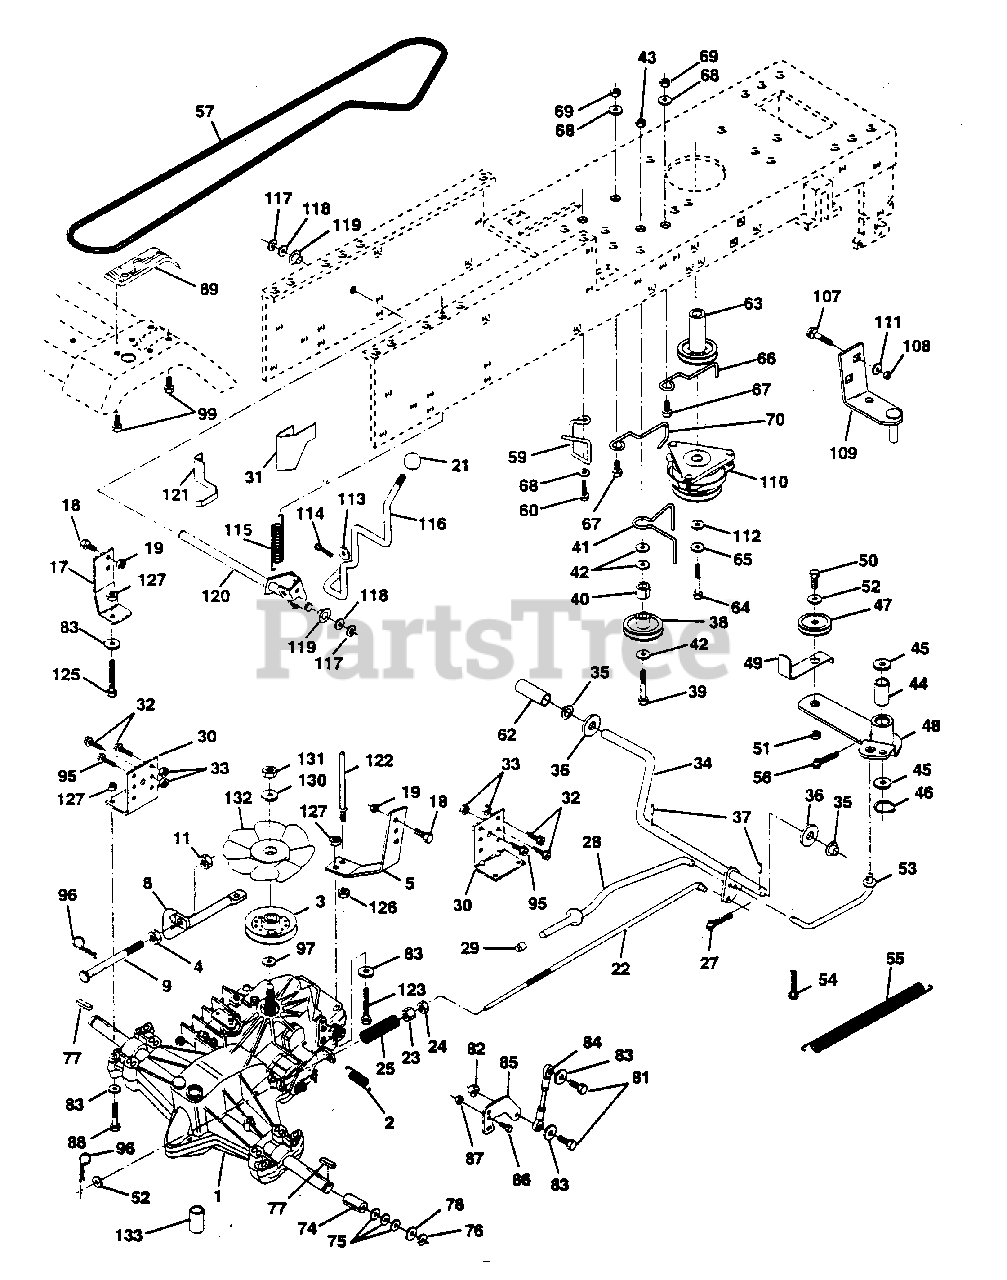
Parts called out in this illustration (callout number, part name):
1	Transaxle Assembly (AYP part number)
2	Spring, Return, Brake (AYP part number)
3	Pulley, Transaxle (AYP part number)
4	Nut Hex Jam 5/16-18 Unc (AYP part number)
5	Strap Torque Rh Hydro 18/20" T (AYP part number)
8	Control Bypass Hydro 18" Tires (AYP part number)
9	Rod Bypass Hydro 18/20" (AYP part number)
11	Nut Lock Hex W/Ins 5/16-18 Unc P (AYP part number)
17	Strap Torque Lh Hydro 18/20" T (AYP part number)
18	Bolt Fin Hex 3/8-16 Unc x 1 Gr. 5 (AYP part number)
19	Nut Lock Hex W/Wsh 3/8-16 Unc (AYP part number)
21	Knob, Duckhead 1/2-13 (AYP part number)
22	Rod, Brake Hydro (AYP part number)
23	Nut (AYP part number)
24	Locknut (AYP part number)
25	Spring, Brake Rod (AYP part number)
27	Pin Cotter 1/8 x 3/4 CAD. (AYP part number)
28	Rod, Parking Brake (AYP part number)
29	Cap, Parking Brake (AYP part number)
30	Bracket, Transaxle (AYP part number)
31	Keeper Belt Lh (AYP part number)
32	Bolt Hex Hd 5/16-18 Unc x 3/4 (AYP part number)
33	Nut Lock Hex W/Ins. 5/16-18 Unc (AYP part number)
34	Shaft, Foot Pedal (AYP part number)
35	Bearing, Nylon (AYP part number)
36	Washer (AYP part number)
37	Pin, Roll (AYP part number)
38	Pulley, Idler, Flat (AYP part number)
39	Bolt (AYP part number)
40	Spacer, Split (AYP part number)
41	Keeper, Belt Retainer (AYP part number)
42	Washer 13/32 x 13/16 x 12 Gauge (AYP part number)
43	Nut (AYP part number)
44	Bearing, Nylon (AYP part number)
45	Washer, Hardened (AYP part number)
46	Ring, Klip (AYP part number)
47	Pulley, Idler, V-Groove
48	Bellcrank Assembly (AYP part number)
49	Retainer, Belt (AYP part number)
50	Bolt (AYP part number)
51	Nut
52	Washer (AYP part number)
53	Link, Clutch (AYP part number)
54	Pin (AYP part number)
55	Spring, Return, Clutch (AYP part number)
56	Pin (AYP part number)
57	V-Belt, Ground Drive (AYP part number)
59	Keeper, Center Span (AYP part number)
60	Screw Thdrol. 3/8-16 x 3/4 Ty. TT (AYP part number)
62	Cover, Pedal (AYP part number)
63	Pulley, Engine (AYP part number)
64	Bolt, Hex (AYP part number)
65	Washer (AYP part number)
66	Keeper Belt Engine (AYP part number)
67	Bolt (AYP part number)
68	Washer 13/32 x 13/16 x 12 Gauge (AYP part number)
69	Nut (AYP part number)
70	Keeper Belt Engine (AYP part number)
74	Spacer, Split (AYP part number)
75	Washer 25/32 x 1-1/4 x 16 Gauge (AYP part number)
76	E-Ring (AYP part number)
77	Key, Square (AYP part number)
78	Washer 25/32 x 1-5/8 x 16 Gauge (AYP part number)
81	Bolt Fin Hex 5/16-18 Unc x 1-1/4 (AYP part number)
82	Nut Lock Hex W/Ins. 5/16-18 Unc P (AYP part number)
83	Washer 11/32 x 3/4 x 16 Ga. (AYP part number)
84	Rod, Tie Hydro 20" Tires (AYP part number)
85	Arm, Control Hydro (AYP part number)
86	Screw Cap Hex 5/16 x 18 x 1 (AYP part number)
87	Nut Lock Hex W/Ins. 5/16-18 Unc P (AYP part number)
88	Bolt Fin Hex 5/16-18 Unc (AYP part number)
89	Console, Shift (AYP part number)
95	Screw, Thdroll. 3/8-16 x 1 Type TT (AYP part number)
96	Retainer Spring 1" Zinc/Cad (AYP part number)
97	Washer 21/32 x 1 x 16 Ga. (AYP part number)
99	Screw (AYP part number)
107	Bolt Carriage 5/16-18
108	Nut, Crownlock 5/16-18
109	Bracket, Asm Mtg Clutch (AYP part number)
110	Clutch, Electric (AYP part number)
111	Washer 11/32 x 5/8 x 12 Ga. (AYP part number)
112	Washer 1-1/2 OD x 15/32 ID x .250 (AYP part number)
113	Washer 17/32 x 3/4 x 16 Ga. (AYP part number)
114	Pin Cotter 1/8 x 1 CAD (AYP part number)
115	Spring Torsion T/A (AYP part number)
116	Rod Shift Fender YT (AYP part number)
117	Ring Klip #5304-62 (AYP part number)
118	Washer 21/32 x 1-1/4 x 16 Ga. (AYP part number)
119	Bushing Rod Steering 629/632 ID (AYP part number)
120	Shaft Asm. Cross Hydro 20" Tires (AYP part number)
121	Keeper Belt Lh Hydro 0750. 18/20" (AYP part number)
122	Keeper Belt Rh Hydro 0750. 18/20" (AYP part number)
123	Bolt Fin Hex 5/16-18 x 2-1/4 (AYP part number)
125	Bolt Fin Hex 5/6-18 Unc x 1-1/2 (AYP part number)
126	Nut Keps Hex 3/8-16 Unc (AYP part number)
127	Nut Lock Hex W/Ins 5/16-18 Unc P (AYP part number)
130	Washer Belleville .501D x 1.50D (AYP part number)
131	Nut Nylon Insert 1/2-20 Unf. (AYP part number)
132	Fan, Hydro 7" (AYP part number)
133	Line Fuel Hydro 4" (AYP part number)
